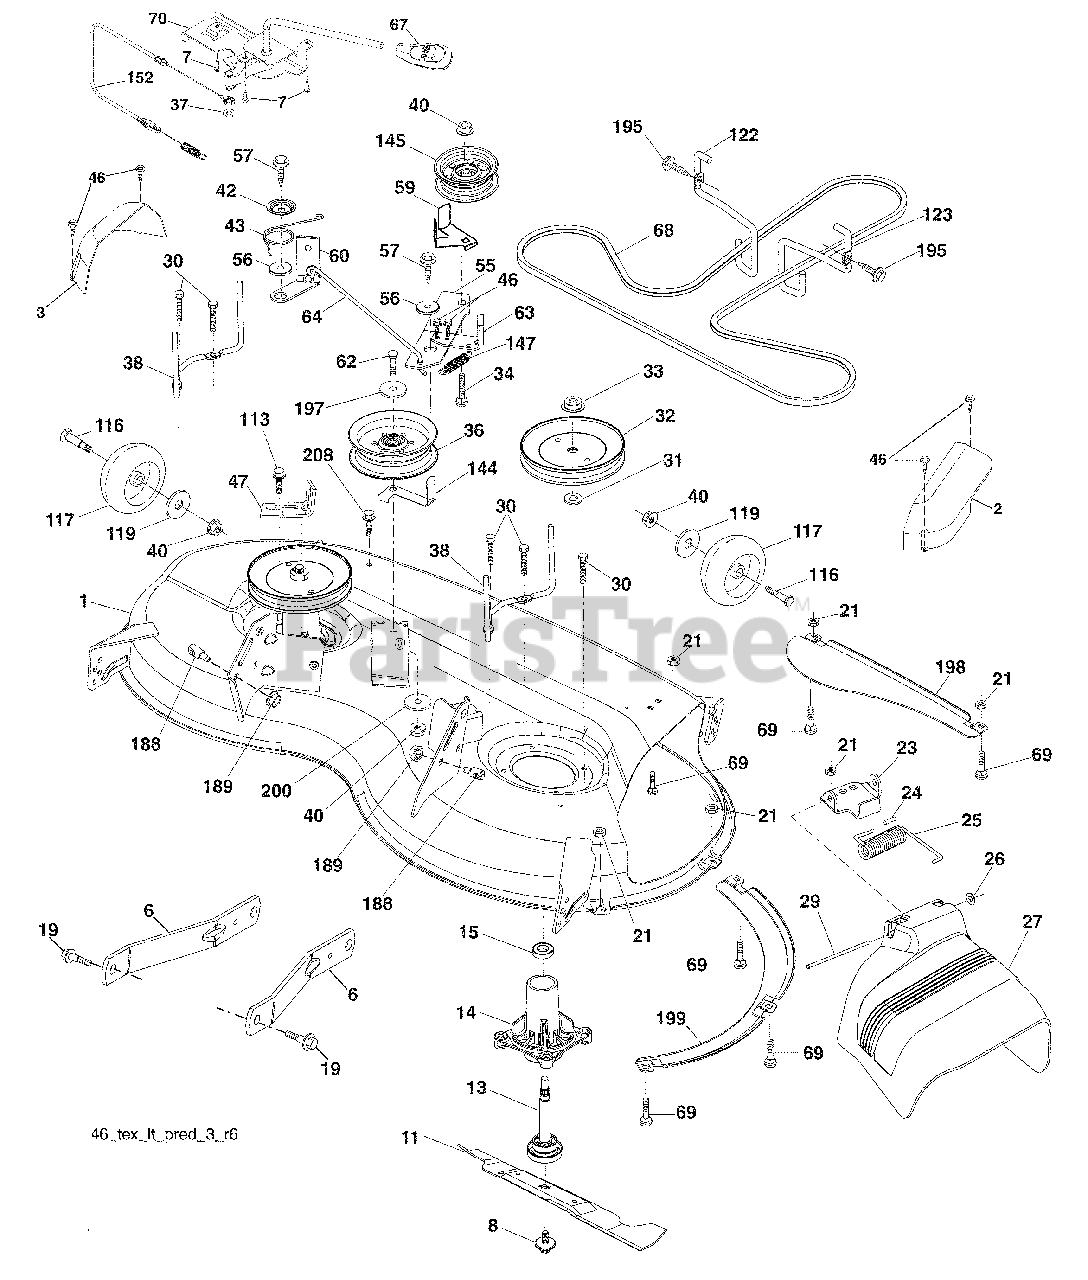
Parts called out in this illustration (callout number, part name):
1	Mower Housing
2	Cover Mandrel RH
3	Cover Mandrel LH
6	Arm Suspension
7	Screw # 10 x 0.750
8	Bolt/Washer asm 7/16-20 unf
11	Blade Mower Hi Lift
13	Shaft Assembly, Mandrel
14	Housing, Mandrel
15	Bearing, Ball, Mandrel
19	Bolt, Shoulder
21	Nut
23	Bracket, Deflector
24	Cap, Sleeve
25	Spring, Torsion, Deflector
27	Shield, Deflector
29	Rod, Hinge
30	Screw Thdrol Rolling Wsh Hd
31	Washer, Spacer
32	Pulley, Mandrel
33	Nut, Toplock, Flanged
34	Bolt Carr Sh. 3/8-16 x 1-1/2 Gr. 5
36	Pulley, Idler, Flat
37	Washer 13/32 x 13/16 x 16 Ga.
38	Keeper Belt LH Mandrel
40	Nut, Lock Flg. 3/8-16 unc
42	Spring Torsion Brake
43	Spring Torsion Retainer
47	Bracket Clutch Cable
55	Arm, Idler
56	Spacer, Retainer
57	Screw Hexwsh Thd 3/8-16 x 1
59	Guard, Tuv Idler (94)
60	Arm Brake Mower LH
62	Bolt 3/8-16 UNC x 2-1/4 Gr. 5
63	Arm Brake Mower
64	Linkage Brake
67	Handle, Clutch Cable
68	V-Belt
69	Bolt
70	Clutch Asm. Cable
113	Screw 5/16-18
116	Bolt, Shoulder
117	Wheel, Gauge
119	Washer 13/32 x 1-1/4 x 12 Ga.
122	Keeper Belt Eng. LH
123	Keeper Belt Eng. RH
144	Keeper Belt
145	Pulley Idler
147	Spring Return
152	Cable Clutch Manual w/Spr.
188	Stud Fastener
189	Nut Lock Hex Flange
195	Screw 3/8-16 x 3/4
197	Washer 13/32 x 13/16 x 12 Ga.
198	Baffle Center Front
199	Baffle Front RH
200	Washer 13/32 x 1 x 1/2 11 Ga.
208	Screw 3/8-16 x 1/2
